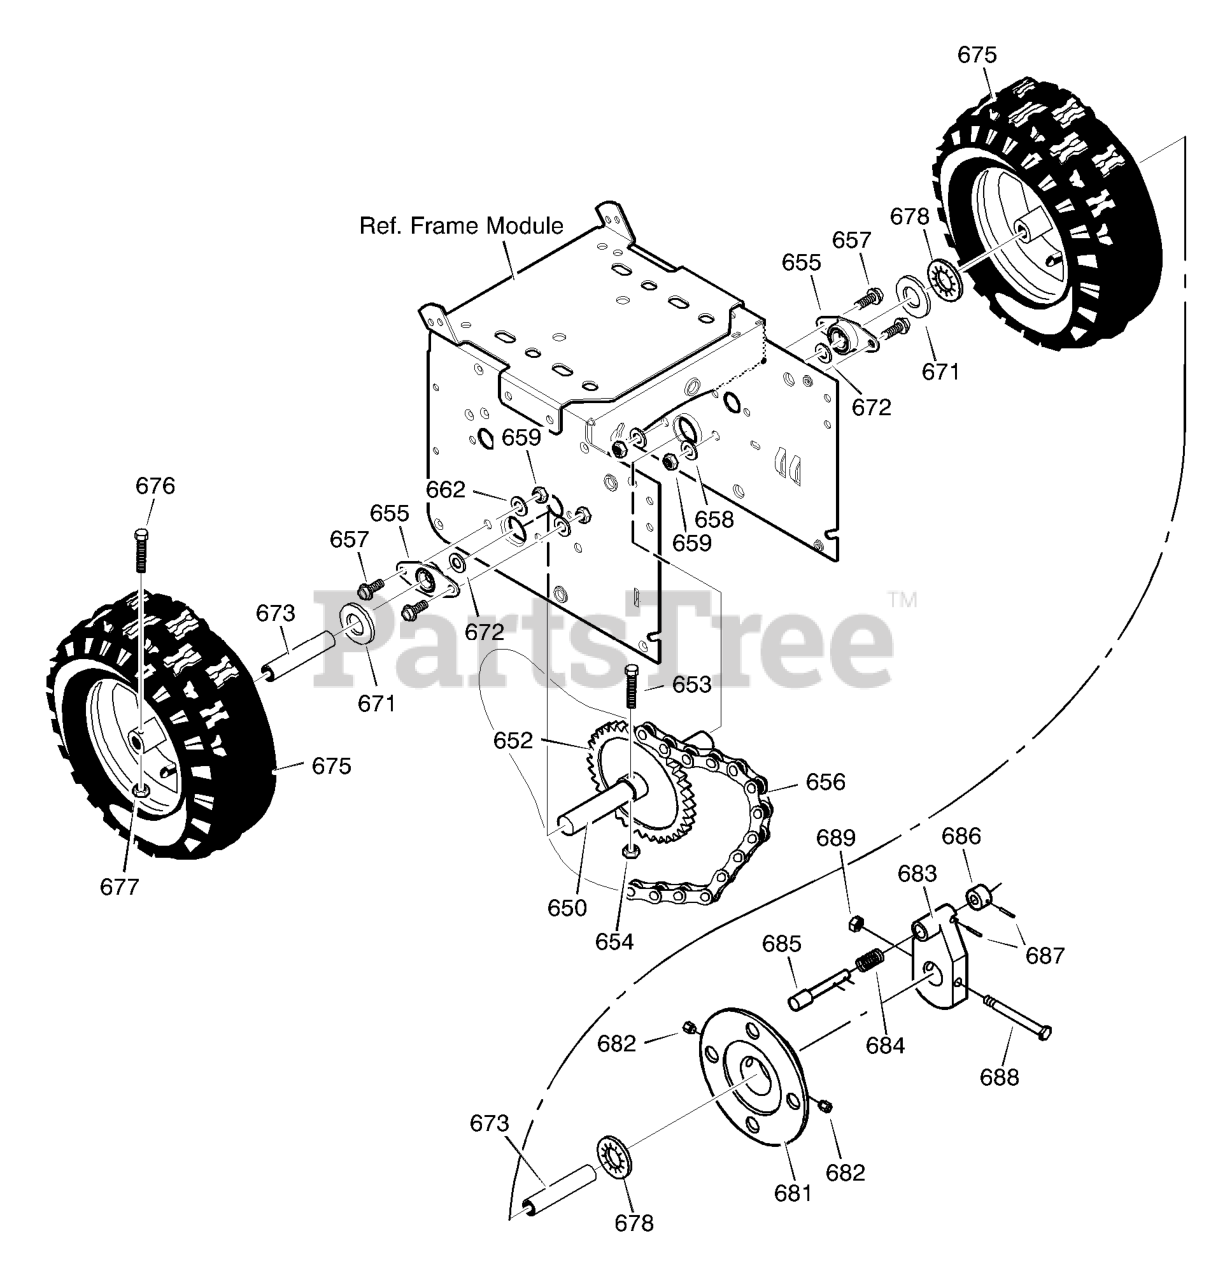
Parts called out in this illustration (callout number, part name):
650	SHAFT, AXLE
652	SPRKT & HUB
653	SCREW, 1/4-20X1.75
654	NUT, 1/4-20 HEX NYLOCK
655	RETAINER & BEARING ASSY
657	SCREW, 3/8"-16x.75
658	WASHER, LOCK
659	NUT, 3/8"-16
671	WASHER, FLAT
673	BUSHING, WHEEL
675	TIRE & RIM -Right
676	SCREW, 1/4-20X1.75 HH
677	NUT, 1/4-20 HEX NYLOCK
678	RING, RET
680	TIRE & RIM -Left
681	DISC, WHEEL
683	HUB, WHEEL LOCK
684	SPRING, COMPRESSION
685	PIN, LOCK
686	KNOB
687	PIN
689	NUT
